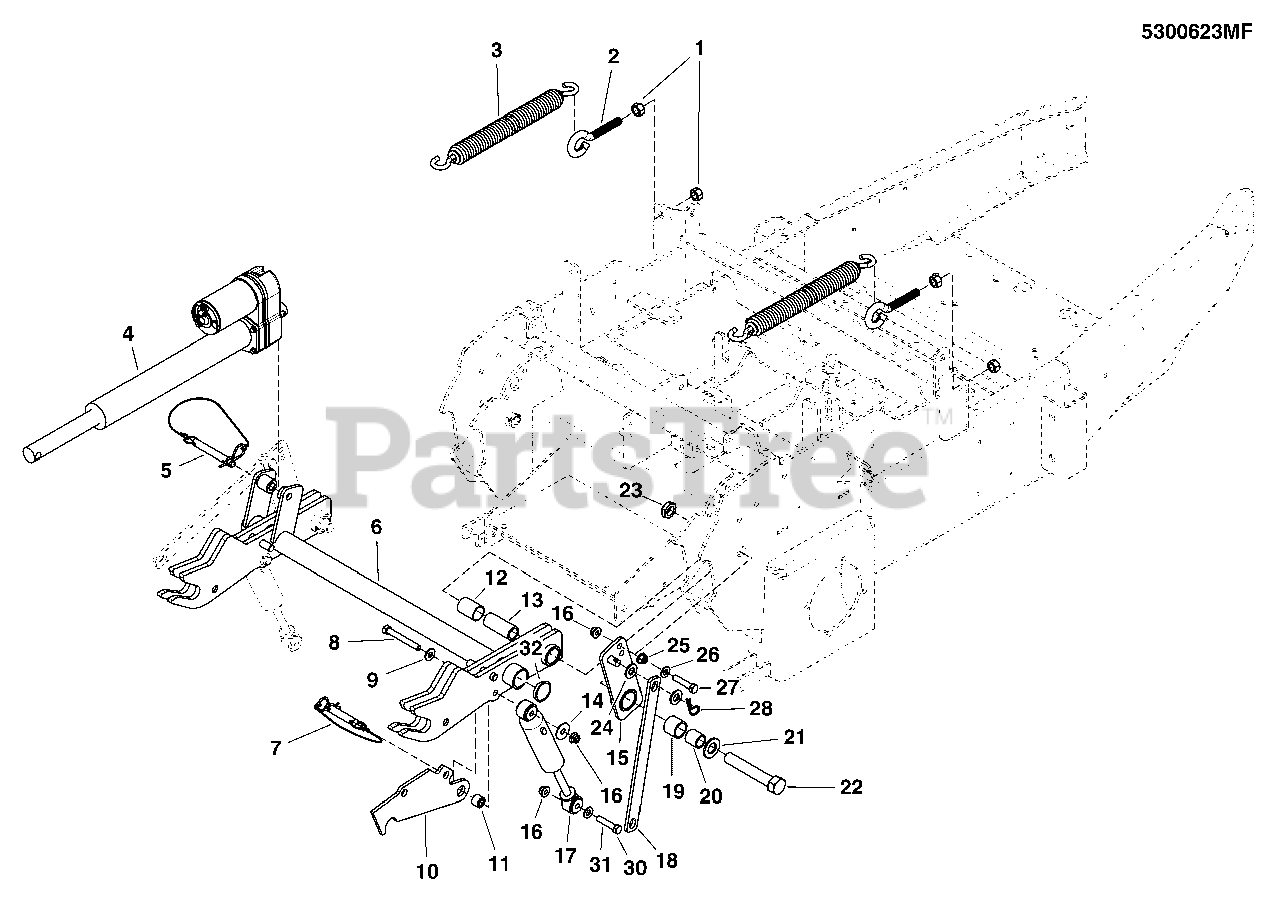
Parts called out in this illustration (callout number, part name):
1	NUT, 1/2-13 HEX
2	EYE BOLT, 1/2-13 X 5.5, 1 EYE, CZ
3	SPRING-EXT, 1.393ODX13.25LGX.218WR
4	ACTUATOR, 12" STROKE, 1600 LBS
5	HITCH PIN ASSY., 1/2 X 3.50
6	WELD, ATTACHMENT MOUNT - RED
7	HITCH PIN ASSEMBLY, 1/2" X 2.50"
8	BOLT, 3/8-16 X 3 GD5 YZ
9	WASHER, 5/16 USS
10	LATCH, FRONT FRAME - RED
11	SPACER, .39 X .75 X .580
12	PIVOT BEARING-1.00 X 1.125 ODX1.50
13	SPACER, .75 X 1.00 X 2.38
14	WASHER-3/8 FENDER
15	WELD, SPRING MOUNT PIVOT - LH - RED
16	NUT, 3/8-16 HEX NYLOCK FLANGE
17	SHOCK ABSORBER, OUT FRONT MOWER
18	BAR, SPRING ASSIST LINK - RED
19	BUSHING, BRASS, 1.00 X 1.25 X 1.00
20	SPACER, .76 X 1.00 X 1.06
21	WASHER, 3/4 SAE
22	BOLT, HEX HD, 3/4-16 X 4-1/2, GD5 YZ
23	NUT, 3/4-16, HEX JAM NYLON LOCK
24	WASHER, 1/2 SAE
25	NUT, 3/8-16 HEX SERRATED FLANGE
26	WASHER, 5/16 USS
27	BOLT, 3/8-16 X 1-3/4 GD5
28	PIN, HAIR, .0915 X 1-7/8
30	BOLT, 3/8-16 X 2-1/4 GD5 YZ
31	WASHER, 3/8 SAE
32	PLUG, PANEL, 1.25 - BLACK
